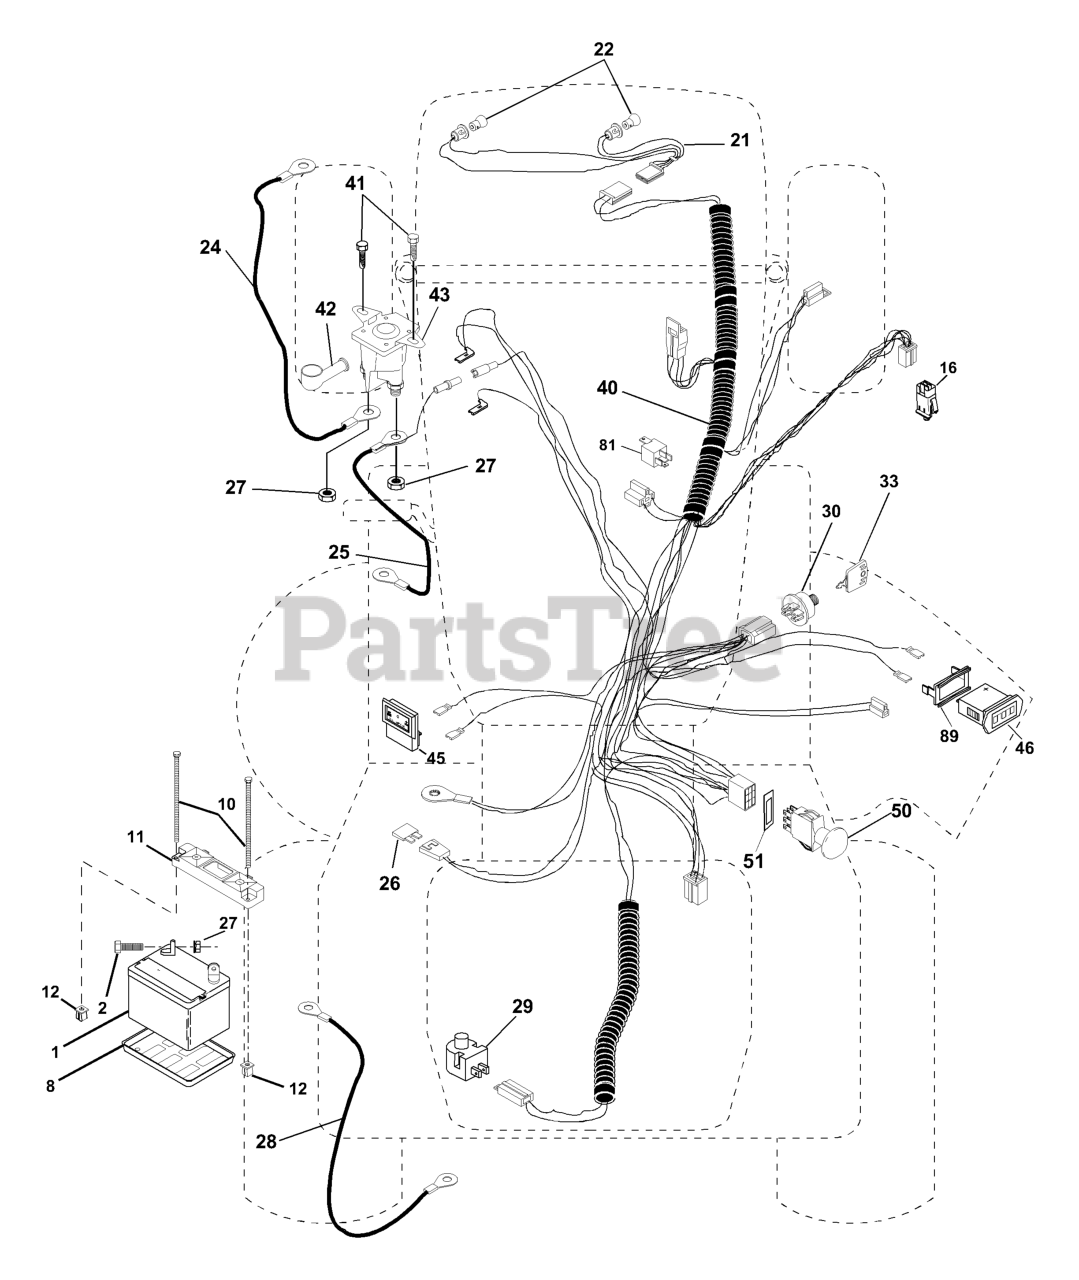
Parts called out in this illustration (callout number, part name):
1	BATTERY 12V .35 AMP
2	BOLT
8	BATTERY TRAY T
10	BOLT, BTR FRT 1/4-20X4-1/2ZINC
11	BATTERY HOLDDOWN FRONT MOUNT
12	NUT, PUSH NYLON 1/4" BATTERY
16	SWITCH INTERLOCK
21	HARNESS ASM, LIGHT W/4152J
24	CABLE, STARTER
25	CABLE, BATTERY
27	NUT
28	CABLE, GROUND
29	PLUNGER SWITCH (COLOR:OLIVE)
30	SWITCH IGN
33	KEY MLD GEN DELTA
40	Harness Ign.
41	SCREW, THD CUT 1/4-20 X 1/2
42	TERMINAL COVER
43	SOLINOID
46	HOUR METER
50	PTO SWITCH
51	FRAME RETAINING RING
62	BULB LIGHT T
81	RELAY.ASSY.T
89	BRACKET SNAP-IN HOURMETER
